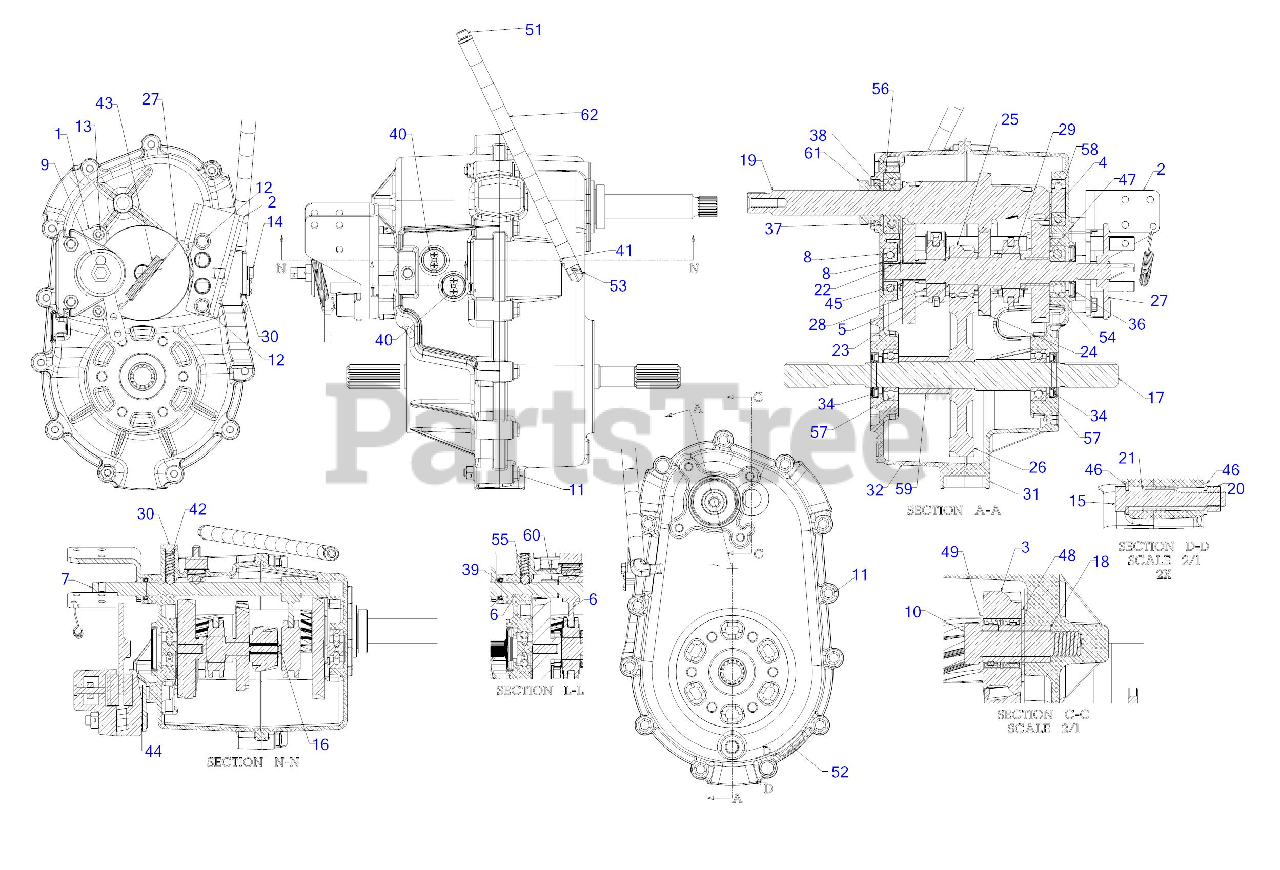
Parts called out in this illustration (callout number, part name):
1	MOUNT BRACKET ASSEMBLY
2	SHIFTER MOUNT BRACKET
3	REVERSE IDLER GEAR ASSEMBLY
4	REVERSE PINION ASSEMBLY
5	LOW SPEED GEAR ASSEMBLY
6	HI-LO YOKE ASSEMBLY
7	LO YOKE ASSEMBLY
8	BEARING ASSEMBLY
9	TRANSFER CASE BRAKE ASSEMBLY
10	SCREW 1/2-13 x 2.00 GR5
11	SCREW 5/16-18 x 1.00
12	SCREW 5/16-18 x .750
13	SCREW 5/16-18 x .625
14	SCREW 1/4-20X.625
15	SCREW 5/16-18 x 2.0 GR5
16	MID SHAFT (4X4)
17	OUTPUT SHAFT (4X4)
18	REVERSE IDLER SHAFT
19	INPUT SHAFT
21	DOWEL BUSHING
22	SNAP RING
23	RETAINING RING
24	HIGH GEAR:4X4:3
25	FINAL PINION GEAR
26	FINAL GEAR
27	DISC BRACKE
28	4X4 LO COLLAR
29	4X4 HI-REV COLLAR
30	DETENT SPRING PLATE
31	TRANSFER CASE HOUSING (RH)
32	TRANSFER HOUSING
34	OIL SEAL 25X46X7
36	OIL SEAL:20X52X7
40	NEUTRAL SAFTEY SWITCH
41	HOSE CLAMP 1/20
42	DETENT SPRING
43	EXTENSION SPRING
44	FLAT WASHER
45	FLAT WASHER
46	FLAT WASHER
47	THRUST WASHER
48	THRUST WASHER
49	FLAT WASHER
51	DUCKBILL VENT-3/8 DIA
52	PLUG FITTING
53	ELBOW FITTING
54	BALL BEARING
55	DETENT BALL .375
56	BALL BEARING
57	PTO SHAFT BALL BEARING
58	BALL BEARING
59	OUTPUT SHAFT SPACER
60	SPACER .566 x .725 x .650
61	INPUT CASE SPACER-25MM
62	FUEL HOSE LOW PERMEATION
